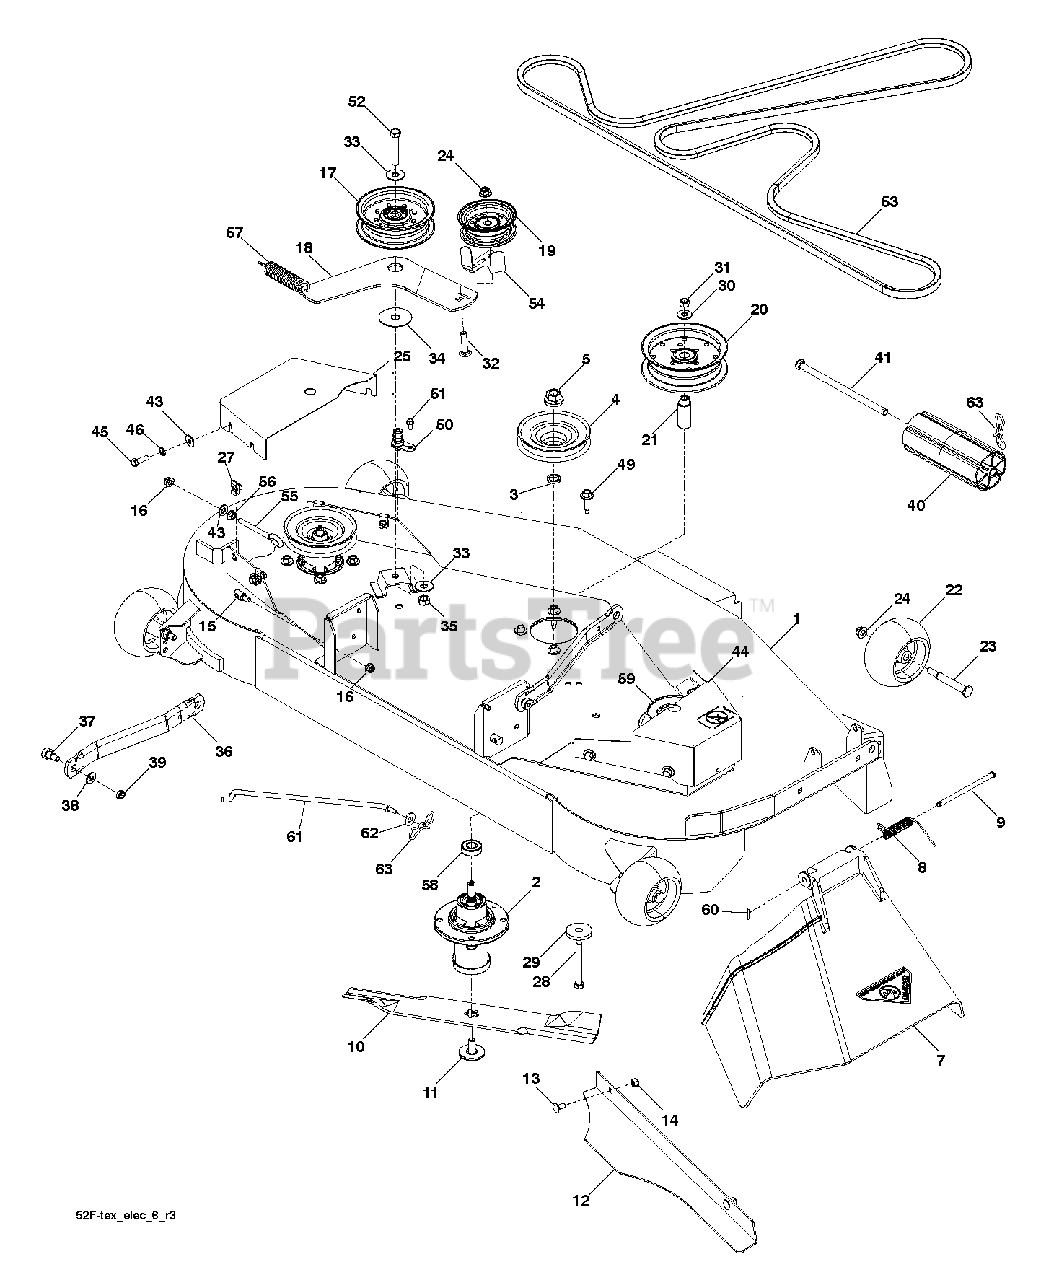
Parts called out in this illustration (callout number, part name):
1	DECK 52" FAB WELDMENT ORANGE
2	MANDREL.DECK.ASSEMBLY
3	WASHER.SPACER.MANDREL
4	PULLEY.DRIVEN.DECK.48'
5	NUT.FLANGE.LOCK.TOP
7	DISCHARGE CHUTE 52"
8	SPRING - TORSION
9	PIN-CLEVIS 5/16 DIA X 5.19 ZD
10	BLADE, 17.75 X 2.5 X .25
11	BOLT.WASHER.ASM.7/16-2
12	PLATE.52".CONFINEMENT.BLACK
13	BOLT
14	NUT.71038.31-18.HEX.NYLOCK
15	STUD.FASTNER.W/ANTI-ROTATE
16	NUT LOCK FLG 3/8-16 UNC
17	PULLEY.IDLER.MWR.STATI.LH
18	ARM, IDLER, 52" BLK
19	PULLEY.IDLER.FLAT
20	PULLEY, IDLER
21	BUSHING, IDLER
22	WHEEL GAGE DONUT
23	BOLT.SHOULDER.3/8-16X3-5/8.
24	NUT 3/8-16 HEX FLG NYLOC ZD
25	SHIELD.BELT.LH.ORANGE
27	U-CLIP 5/16-18 NUT RETAINER
28	HCS 3/8-16 X 3-1/2 GR5 ZD
29	SPINDLE WASHER
30	WASHER 3/8 FLAT
31	NUT 3/8-16 NYLOC
32	RHSNB 3/8-16X1-3/4
33	WASHER 7/16 FLAT ZD
35	NUT.LOCK.FLANGE.7/16
36	ARM.SUSPENSION.MOWER
37	SB 3/8-16 X 3/8 SKT HD ZD
38	WASHER
39	NUT HEX 3/8-16 NYLON, THIN
40	NOSE ROLLER 48"
41	ROD.ROLLER.NOSE.NARROW.48"
43	WASHER
44	SHIELD.BELT.RH.52.ORANGE
45	BOLT.FIN.HEX.5/16-18UNC X 1.00
46	WASH.5/16.SLW.ZD
49	BOLT.HEX.WASHR.HED.313-18X1.19
50	PORT.WASHOUT
51	SCREW
52	BOLT.HEX.7/16-14
53	BELT, 143.5" EL
54	GUARD, BELT
55	EYE BOLT 5/16 X 3.50
56	NUT 5/16C WHIZ
59	RP PULLEY, COLLECTION 48
60	RETAINER CLIP
61	ROD.ANTI.SWAY.48/54"TE
62	WASHER
63	PIN.COTTER.5/16.BOW TI
